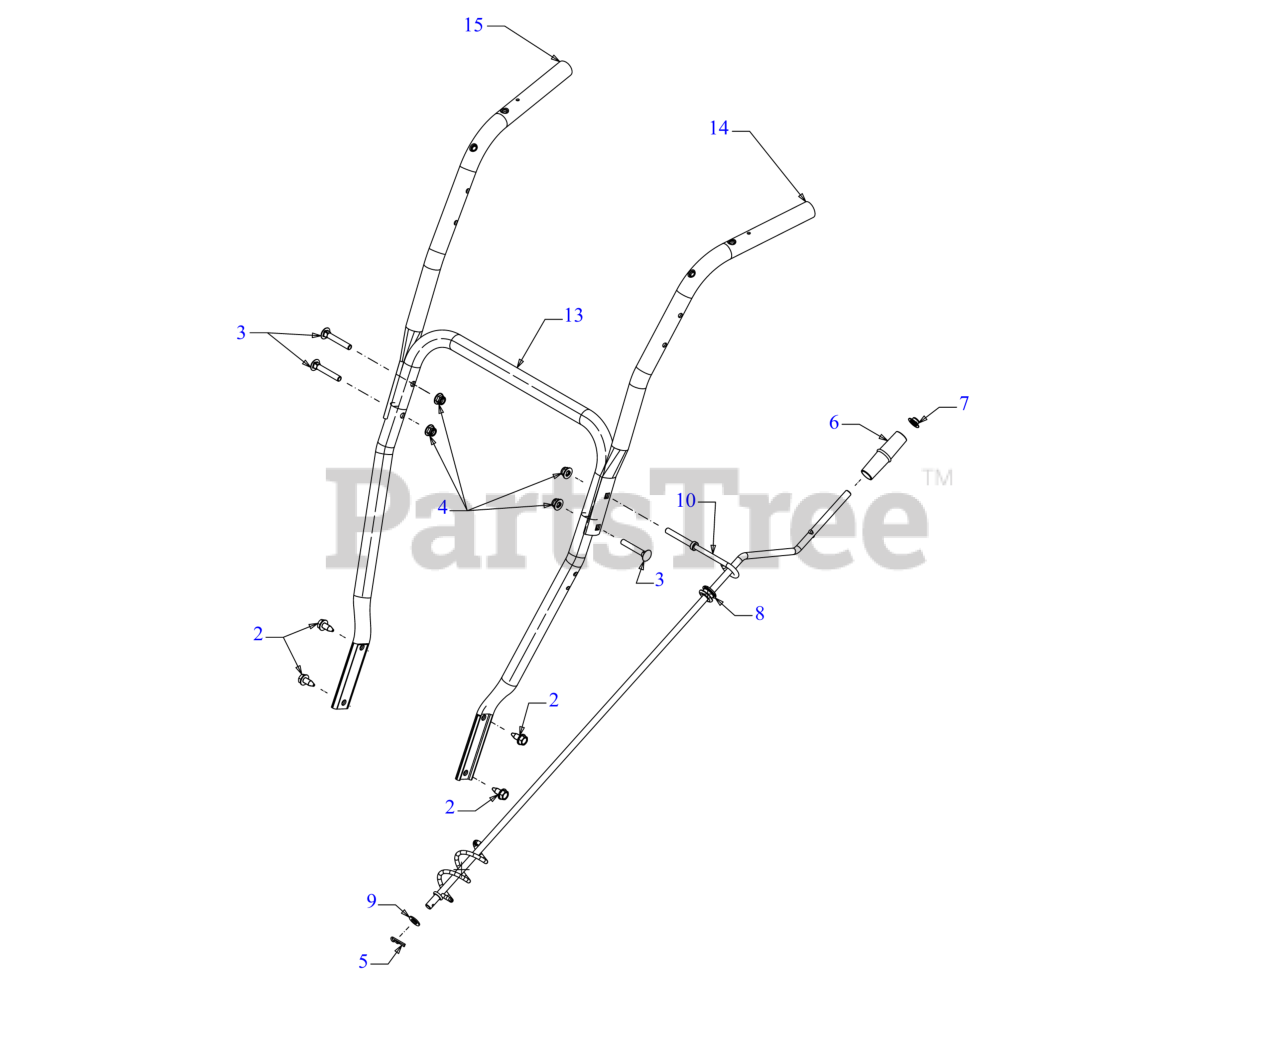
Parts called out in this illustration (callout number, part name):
1	CHUTE CRANK ASSEMBLY (POWDER BLACK)
2	SCREW 5/16-18 x .750
3	CARRIAGE BOLT 5/16-18 x 2.00 GR5
4	FLANGE LOCK NUT 5/16-18
5	COTTER PIN .072 DIA. 1.13 LG
6	CHUTE CRANK KNOB
7	PUSH NUT
9	FLAT WASHER
10	CHUTE CRANK EYEBOLT
14	UPPER HANDLE (LH)
15	UPPER HANDLE (RH)
